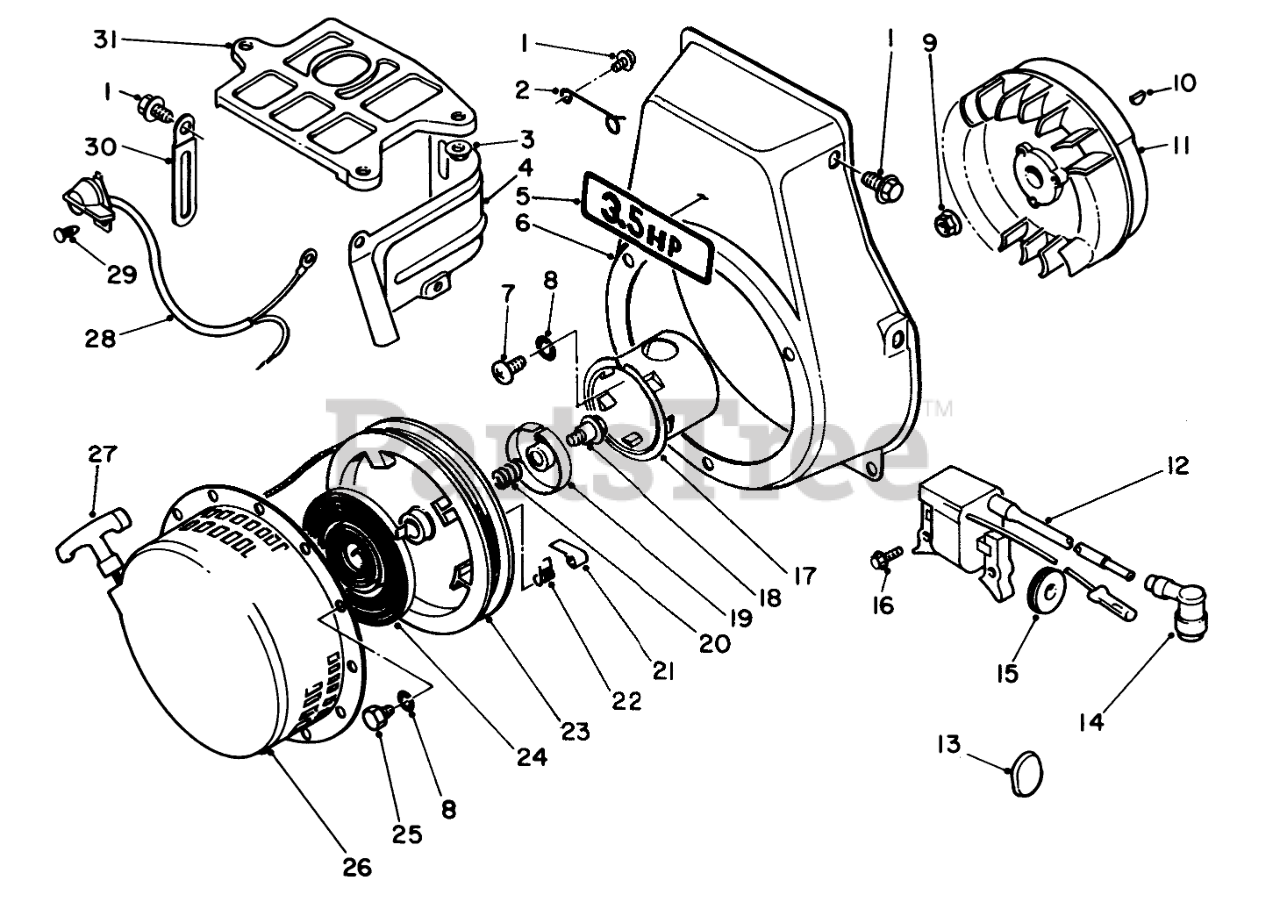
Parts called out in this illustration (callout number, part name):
2	CLAMP
4	Cowling-Side
5	Decal-3.5 H.P.
6	Cover-Cooling Fan
7	Screw
8	LOCKWASHER
11	Flywheel
12	Coil Assembly (Solid State) (Incl. Ref. #14 & 15
14	SPARK PLUG CAP
15	Grommet
17	Pulley-Starter
19	Retainer
20	SPRING
22	SPRING
23	Reel
24	SPRING
26	Recoil Starter Assembly (Incl. Ref. #8, 18-25 & 27)
27	Grip-Hand
28	SWITCH
30	CLAMP
31	Cowling-Upper
